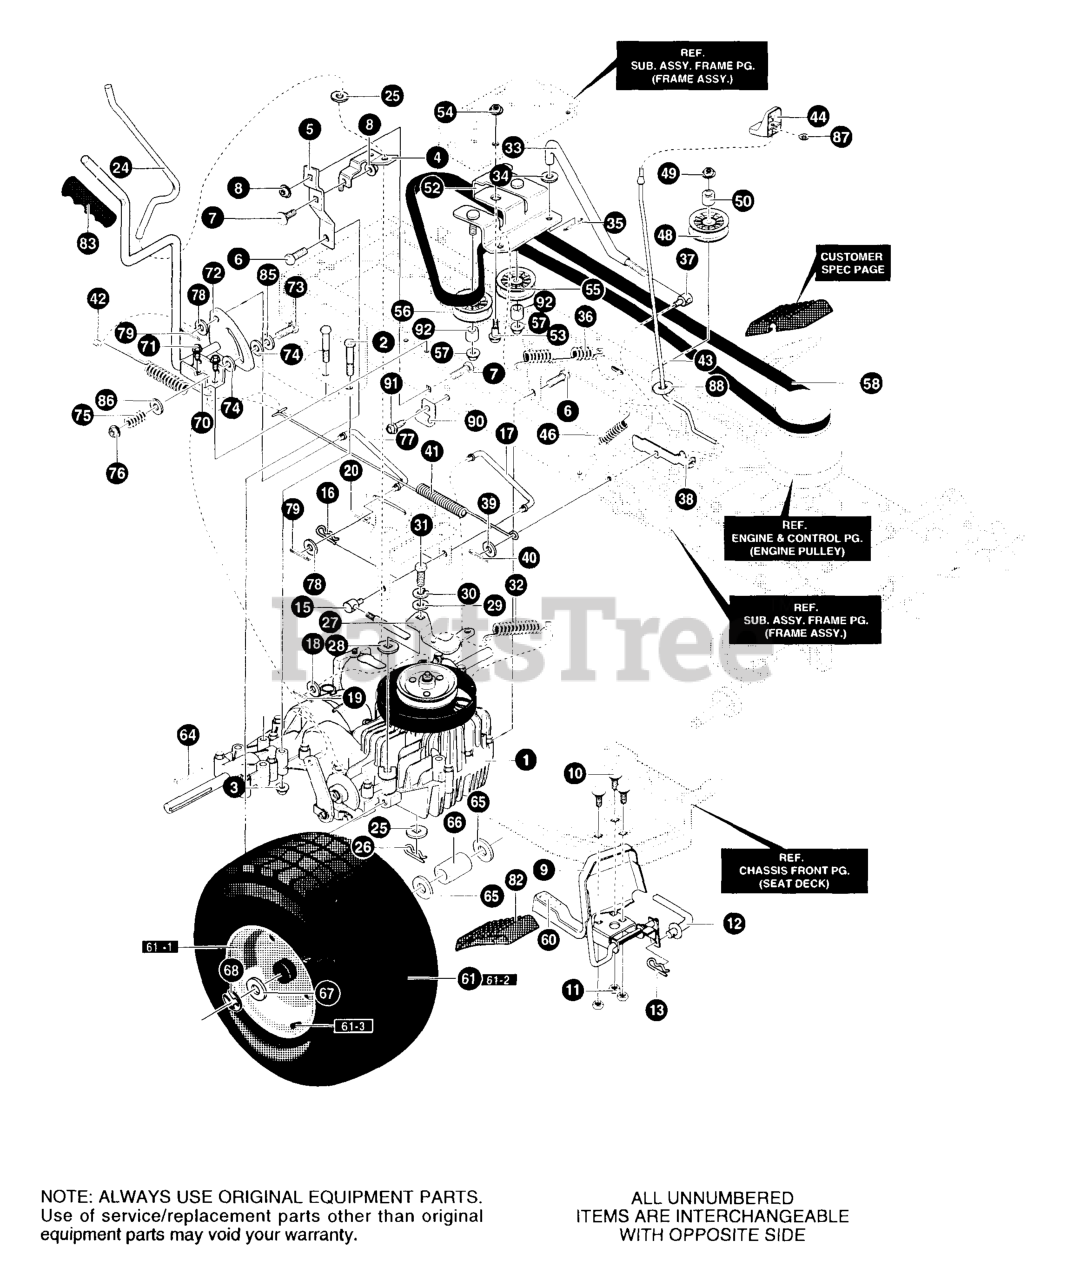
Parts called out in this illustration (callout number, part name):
1	Transaxle, Peerless **
2	SCREW, 5/16-18 x 2.50
3	NUT, 5/16-18 WDFLLK
4	DISCONNECT BRACKET
5	TORQUE STRAP-RIGHT PEERLESS **
6	SCREW, 5/16-18 x 0.75
7	BOLT, 5/16-18X.63 CARR.
8	NUT, 5/16-18 WDFLLK
9	PEDAL ASSY HYDRO
10	BOLT, 5/16-18X.75 CARR.
11	NUT, 5/16-18 HEXWDFLLK WHIZ
12	ROD, PEDAL LINK
13	PIN, HAIR
15	NUT, ADJUSTING 1/2-13UNC
16	PIN, HAIR.38X DIA.X1.64LG
17	ROD, HYDRO LINK
18	WASHER, FLAT
19	PIN, COTTER .094DIAX.75LG
20	PIN, HAIR
24	ROD, DISCONNECT
25	WASHER, FLAT .344X.62X.06
26	PIN, COTTER .094DIAX.75LG
27	ARM, DISCONNECT
28	WASHER, .388/.393SQX1.00X.065
29	WASHER, FLAT.256X.75X.130
30	WASHER (18X32)
31	SCREW, 1/4-28X.750
32	SPRING, EXTENSION 2.26LG
33	ROD, CLUTCH
34	WASHER, FLAT .344 x .62 x .06
35	PIN, COTTER .094DIAX.75LG
36	SPRING, CLUTCH HYDRO
37	NUT, ADJUSTING
38	LATCH, PARKING BRAKE
39	WASHER, FLAT .406 x .81 x 16 GA
40	PIN, COTTER .094DIAX.75
41	SPRING, EXTENSION 23.10LG
42	SPRING, TENSION 3.984X.530
43	ROD, PARKING BRAKE
44	KNOB, PARKING BRAKE
46	SPRING, TENSION .375X1.50X.
48	PULLEY, IDLER 2.75 DIA
49	NUT, 3/8-16 HWDFLLK MACK
50	SPACER, 1/2 TO 17MM
52	ASM.BRACKET IDLER
53	BOLT, .50X.75 HHSH 3/8-16
54	NUT, 3/8-16 HWDFLLK MACK
55	PULLEY, IDLER
56	PULLEY, IDLER
57	NUT, 3/8-16 HWDFLLK MACK
58	BELT, MOTION DRIVE HYDRO
60	PAD, TOE SANDPAPER
61	TIRE & RIM 20X10-8
61-1	TIRE 20X10-8
61-2	RIM, CARL
61-3	VALVE STEM
64	KEY, SQUARE .187SQX2.25 LG
65	WASHER, FLAT .760 x 1.25 x .065
66	SPACER.87X1.78
67	WASHER, FLAT .765 x 1.81 x .059
68	E-RING .574IDX.050/.750SH 11X3
70	BRACKET, MOUNT HAND CONTROL
71	SCREW 5/16-18X.75
72	ASM. LEVER HAND CRUISE
73	BOLT, .375X1.59 HHSH 5/16-18X.5
74	WASHER, FRICTION
75	SPRING - COMP.875LONGX.0915 WIRE
76	NUT, 5/16-18 WDFLLK
77	LINK, CRUISE CONTROL
78	WASHER, FLAT .344 x .62 x .06
79	COTTER PIN.094DIAX.75LG
82	PAD, SPEED CTRL PED
83	GRIP 7/16"
85	WASHER, FLAT .390 x 1.25 x .119
86	WASHER, FLAT .391 X1.00X.083
87	PUSHNUT,.240DIA STUD
88	WASHER, FLAT .281X.63X.065
90	RETAINER, .31IDX.62X.03 WIRE
91	SCREW, 5/16-18 x 0.75 HHWATAP
92	SPACER, 1/2 TO 17MM
